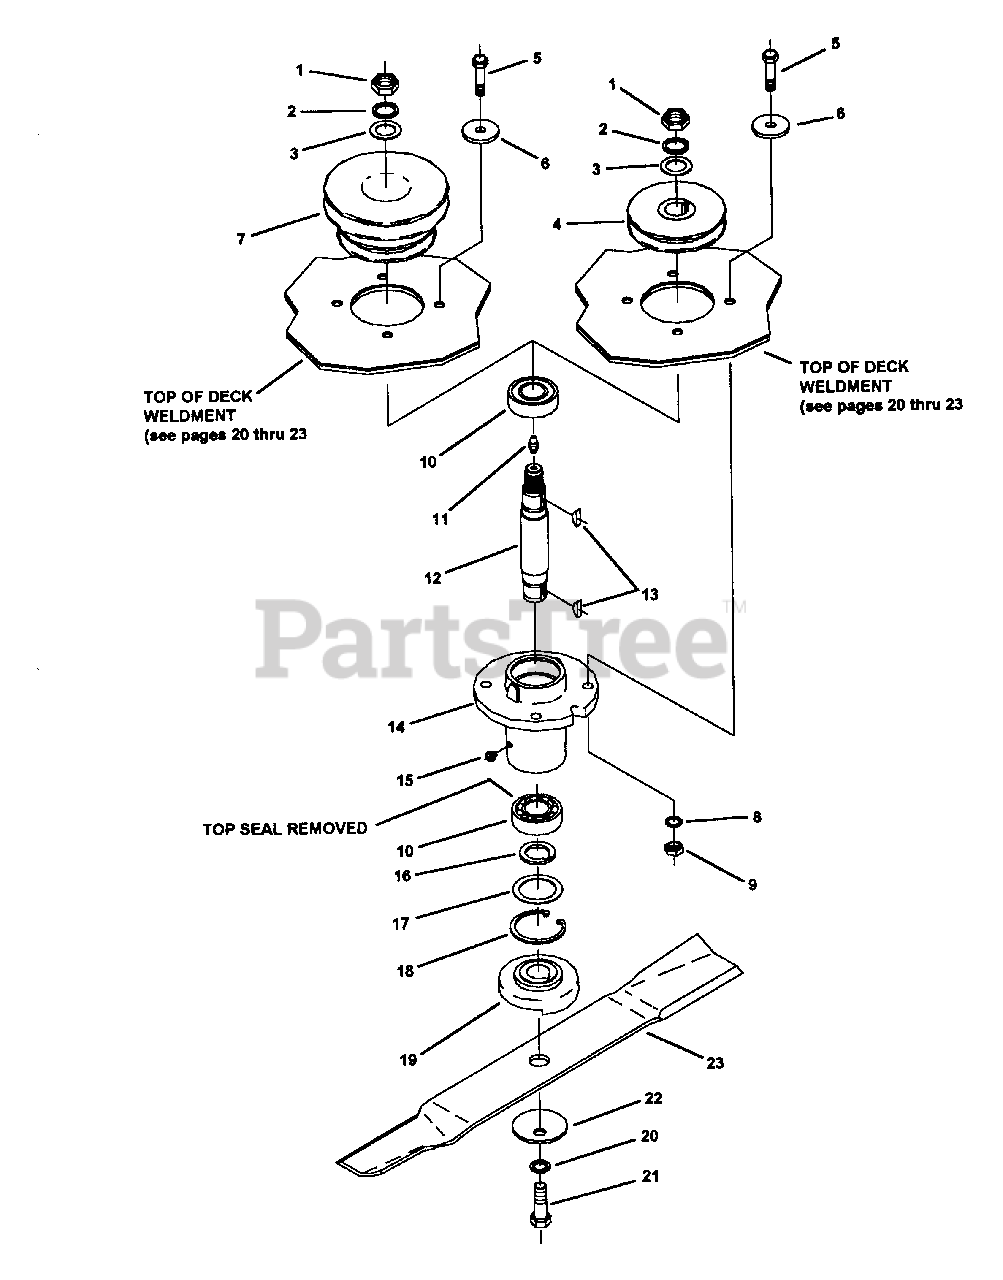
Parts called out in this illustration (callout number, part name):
1	NUT, HEX JAM, 3/4-16 UNF
2	LOCKWASHER, 3/4" STD. SPLIT SPRING
4	PULLEY, 1 GROOVE 4" O.D.
5	BOLT, 3/8-24 X 1-1/2" GR. 5
6	SPINDLE SPACER REINFORCEMENT
7	4-1/2" O.D., 48" DECK
7	5-3/8" O.D., 60" DECK
8	LOCKWASHER, 3/8" HEAVY SPRING TYPE
9	LOCKNUT, HEX. 3/8"-24 YZ GR5
9	DECK SPINDLE ASSEMBLY
10	BEARING, #6205-2RS
11	GREASE FITTING, 1/4-28 SELF TAP
12	SPINDLE SHAFT
13	WOODRUFF KEY, UASS #806, 1/4 X 3/4"
16	ARBOR SPACER
17	WASHER SEAL
18	SNAP RING, INTERNAL, 52 MM BORE
19	BLADE SPACER
20	LOCKWASHER, 1/2" STD. SPLIT SPRING
21	BOLT, 1/2-13 X 1-1/2" GR. 5
22	WASHER, 1/2" CUPPED
23	BLADE, LOW LIFT, 17" CUT, 48" DECK
23	BLADE, LOW LIFT, 21" CUT, 60" DECK
23	BLADE, HIGH LIFT, 17" CUT, 48" DECK
23	BLADE, HIGH LIFT, 21" CUT, 60" DECK
